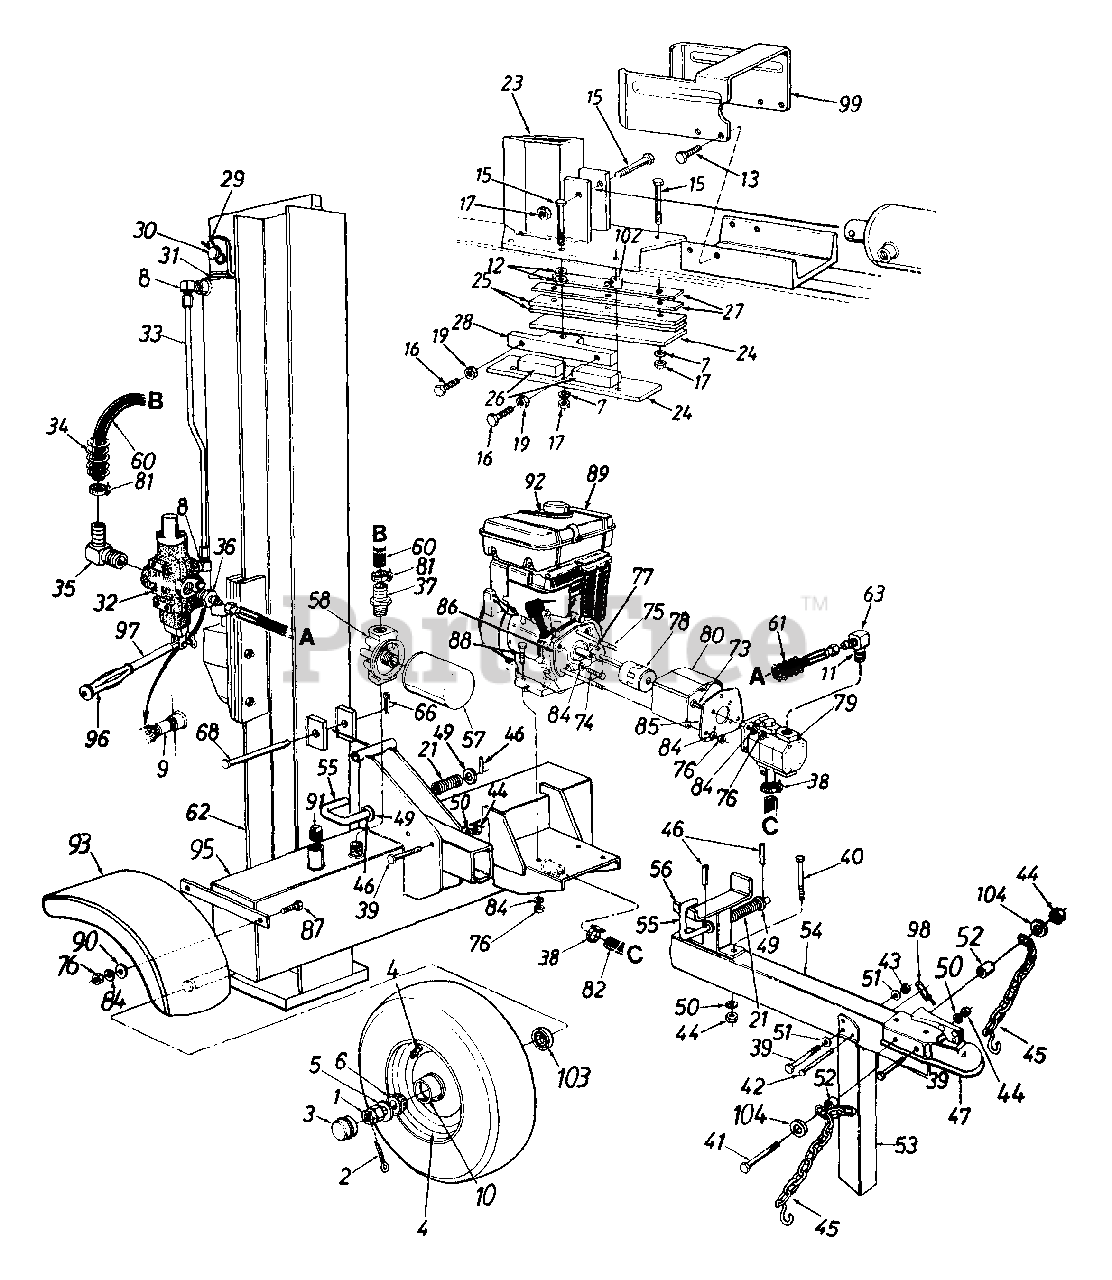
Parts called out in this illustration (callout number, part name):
1	Slotted Nut 3/4-16 Thd.
2	Cotter pin 5/32" Dia.
5	Fl-Wash. .76" I.D. x 1.5" O.D.
6	Bearing Cone
7	L-Wash. 1/2" I.D.
8	90ø Solid Male Adaptor
9	Pipe Nipple 1/2 NPT
10	Bearing Cup
11	90ø Male Adapter
12	Fl-Wash. .531" I.D. x .94" O.D.
13	Hex Cap Scr. 3/8-16 x 1" Lg.
15	Hex Bolt 1/2-20 x 2.75" Lg. (Grade 8)
16	Hex Bolt 3/8-24 x 1.5" Lg.
17	Hex L-Nut 1/2-20 Thd.
19	Hex Jam Nut 3/8-24 Thd. (Grade 5)
21	Comp. Spring 4" Lg.
26	Adjustable Gib
29	External Cotter Pin
30	Cylinder Mounting Pin
33	Metal Pressure Tube
34	Hose Guard
35	Return Elbow
37	3/4" Hose Barb.
39	Hex Bolt 3/8-16 x 3" Lg. (Grade 8)
40	Hex Bolt 3/8-16 x 4" Lg.
41	Hex Bolt 3/8-16 x 4.25" Lg. (Grade 5)
42	Clevis Pin 5/16 x 2.5" Lg.
43	Hex L-Nut 3/8-16 Thd.
44	Hex Nut 3/8-16 Thd.
45	Chain - Tow Hitch
47	Hitch Coupler
49	Fl-Wash. .635" I.D. x .93" O.D.
50	L-Wash. 3/8" I.D.
51	Fl-Wash. .406" I.D. x .75" O.D.
52	Spacer .44" Lg.
57	Filter Element
58	Filter Head
60	Return Hose 3/4" I.D. x 44" Lg.
61	Hose Guard
66	Cotter Pin 1/8" Dia.
68	Hinge Pin 1/2 x 4.8" Lg.
73	Hex Bolt 5/16-24 x 1" Lg.
74	Hex Bolt 5/16-24 x .62" Lg.
75	Hex Bolt 5/16-24 x 4" Lg.
76	Hex Nut 5/16-24 Thd.
77	Sq.-Key 3/16" x .75"
78	Flexible Coupling
79	Gear Pump
80	Coupling Shield
81	Hose Clamp 5/8"
82	Suction Hose
84	L-Wash. 5/16" I.D.
87	Hex Bolt 5/16-24 x .75" Lg.
88	Hex Bolt 5/16-24 x 1.75" Lg.
89	Engine
90	Fl-Wash. .344" I.D. x .875" O.D.
91	L-Vent Pipe Plug
92	Spark Plug Boot
97	Control Handle
102	Spacer 1/2" I.D. x .86" Lg.
103	Bearing Seal Only
104	Fl-Wash. 3/8" I.D. x .87" O.D.
